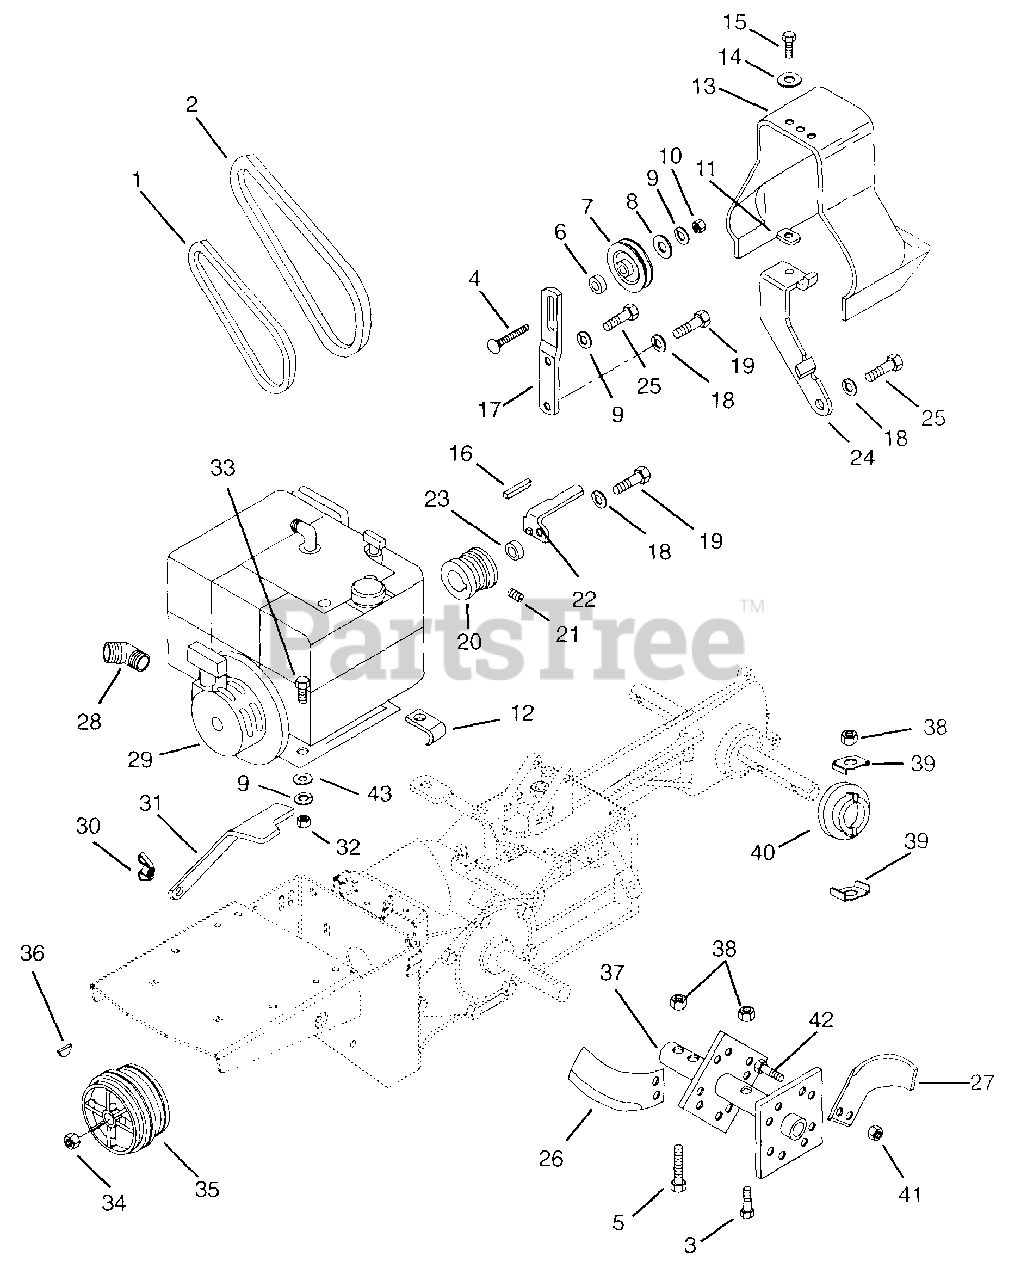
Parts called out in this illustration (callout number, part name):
1	V-BELT, SAE 380-RAW EDGE (SET)
2	V-BELT, 3L-COGGED
3	BLT-HEX .38-16X2.00 GR8 YWZC
4	BLT-RDHDSQSHK .31-18X1.38 GR5Y
5	BLT-HEX .38-16X2.75 GR8 YWZC
6	SPCR, BRG .315X.50X.688X.281
7	IDLER
8	@WSHR-FL-STL.38X.875X.083 YWZC
9	@WSHR-LK .31X.078 REG YWZC
10	@NUT-HEX .31-18 YWZC
11	NUT-SPEED U-TYPE .250-20
12	J-CLAMP
13	BELT GUARD W/DECALS
14	@WSHR-FL-STL.281X.62X.065 YWZC
15	@BLT-HEX .25-20X.50 GR5 YWZC
16	KEY-SQ .25 X 1.25 X .25 SAE
17	REVERSE IDLER BRACKET
18	@WSHR-LK .38X.094 REG YWZC
19	@BLT-HEX .38-16X.75 GR5 YWZC
20	ENGINE SHEAVE
21	SCR-SET .32-18X.38 SKHCUPNL OH
22	BELT FINGER
23	BSHG-SLV .391X.688X.140
24	BELT COVER BRACKET
25	BLT-HEX .31-24X.75 YWZC GR5
26	R KNIFE TINE
27	L KNIFE TINE
28	ELBOW .375X45 STREET
29	ENGINE, B&S 8HP MODEL 196432
30	NUT-NYLK WING .312-18 YWZC
31	BELT FINGER
32	@NUT-HEX .31-18 YWZC
33	@BLT-HEX .31-18X2.00 GR5 YWZC
34	NUT-JAM CTRLK .75-16 YWZC
35	DRIVE SHEAVE
36	KEY-FTHR .188X1.25X.187 SAE
37	INNER TINE HUB
38	@NUT-LK-CTR .38-16 YWZC
40	DUST CAP
41	NUT-LK-TOP .437-14 GR C PL
42	BLT-HEX .44-14X1.00 GR5
43	@WSHR-FL-STL.38X.875X.083 YWZC
